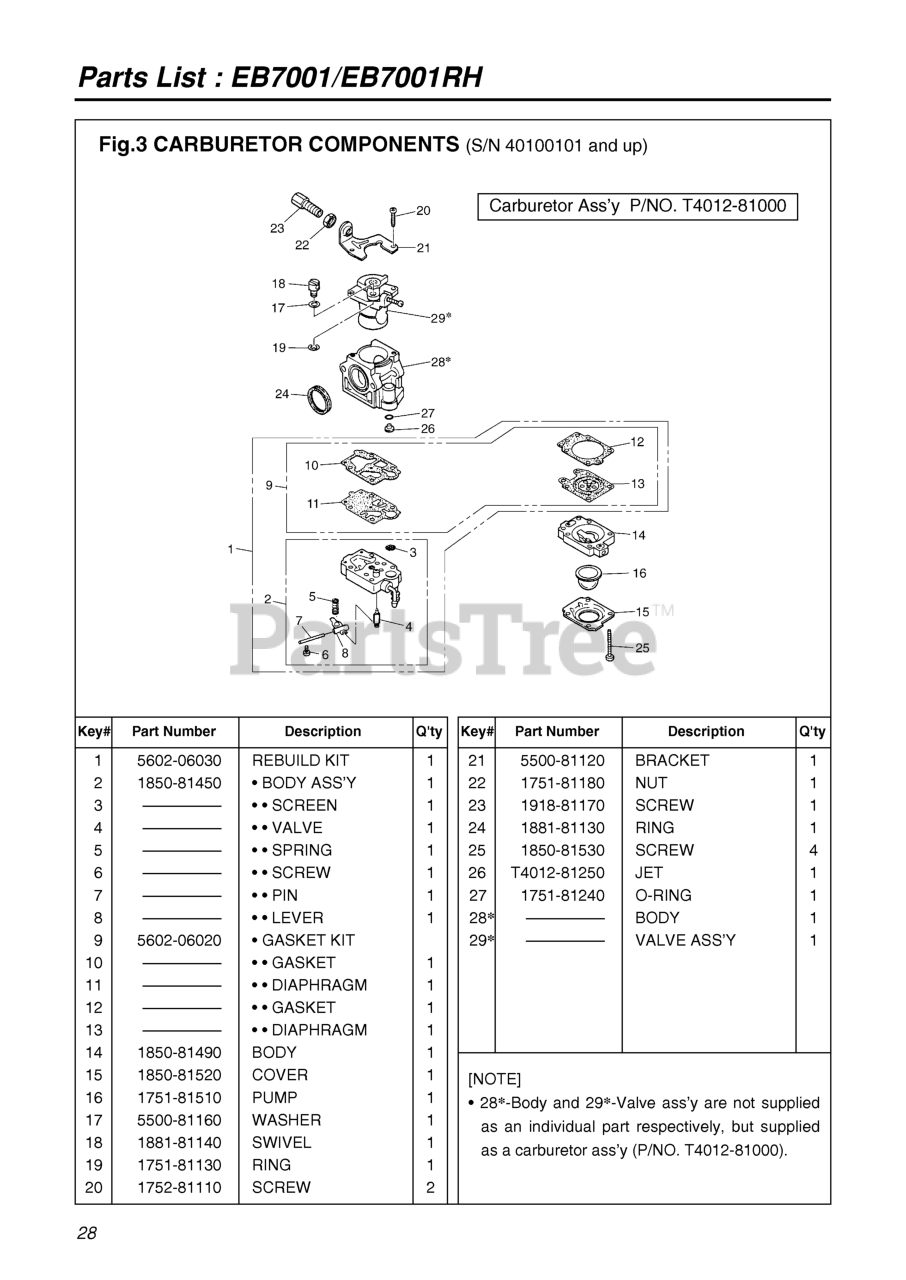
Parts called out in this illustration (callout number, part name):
2	BODY, PUMP
3	SCREEN
4	VALVE
5	SPRING
6	SCREW
7	PIN
8	LEVER
10	GASKET
11	DIAPHRAGM
12	GASKET
13	DIAPHRAGM
14	BODY, PURGE
15	COVER, PUMP
16	PUMP, PRIMING
17	WASHER
18	SWIVEL
19	RING
20	SCREW
22	NUT, CABLE ADJUSTER
23	SCREW, CABLE ADJUSTER
24	RING, PACKING
25	SCREW
26	JET
27	RING, O
28	CARBURETOR (WYK-123-1)
29	CARBURETOR (WYK-123-1)
NI	CARBURETOR (WYK-123-1)
